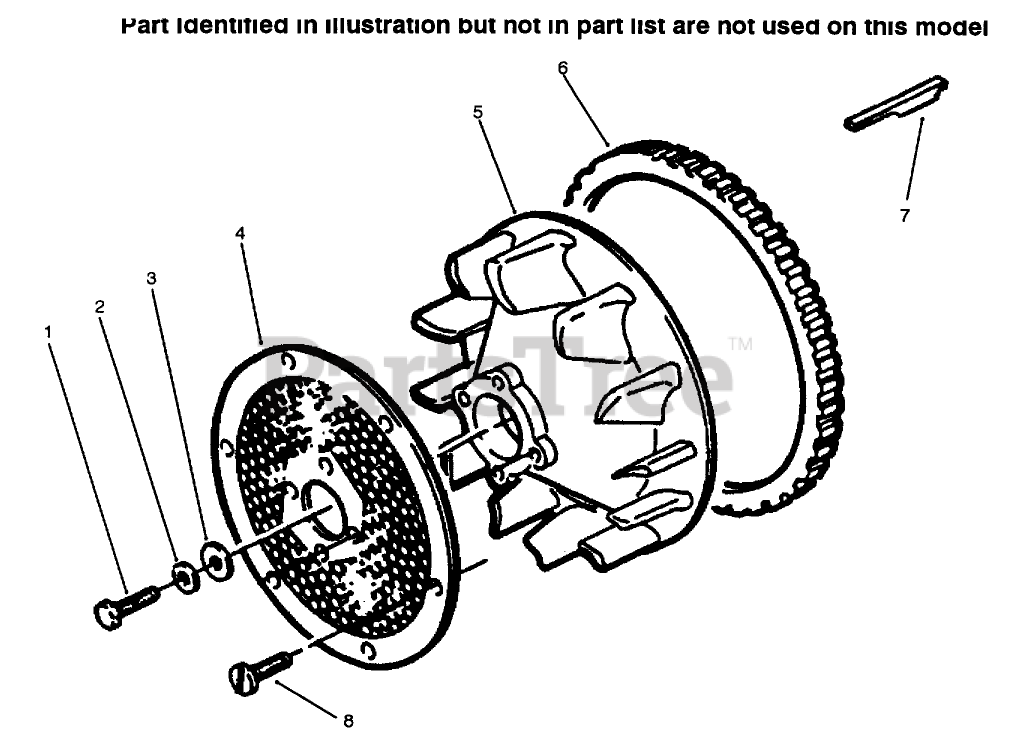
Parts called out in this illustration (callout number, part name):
2	WASHER-FLAT
3	WASHER-FLAT
4	SCREEN-AIR INLET
7	KEY-FLYWHEEL
